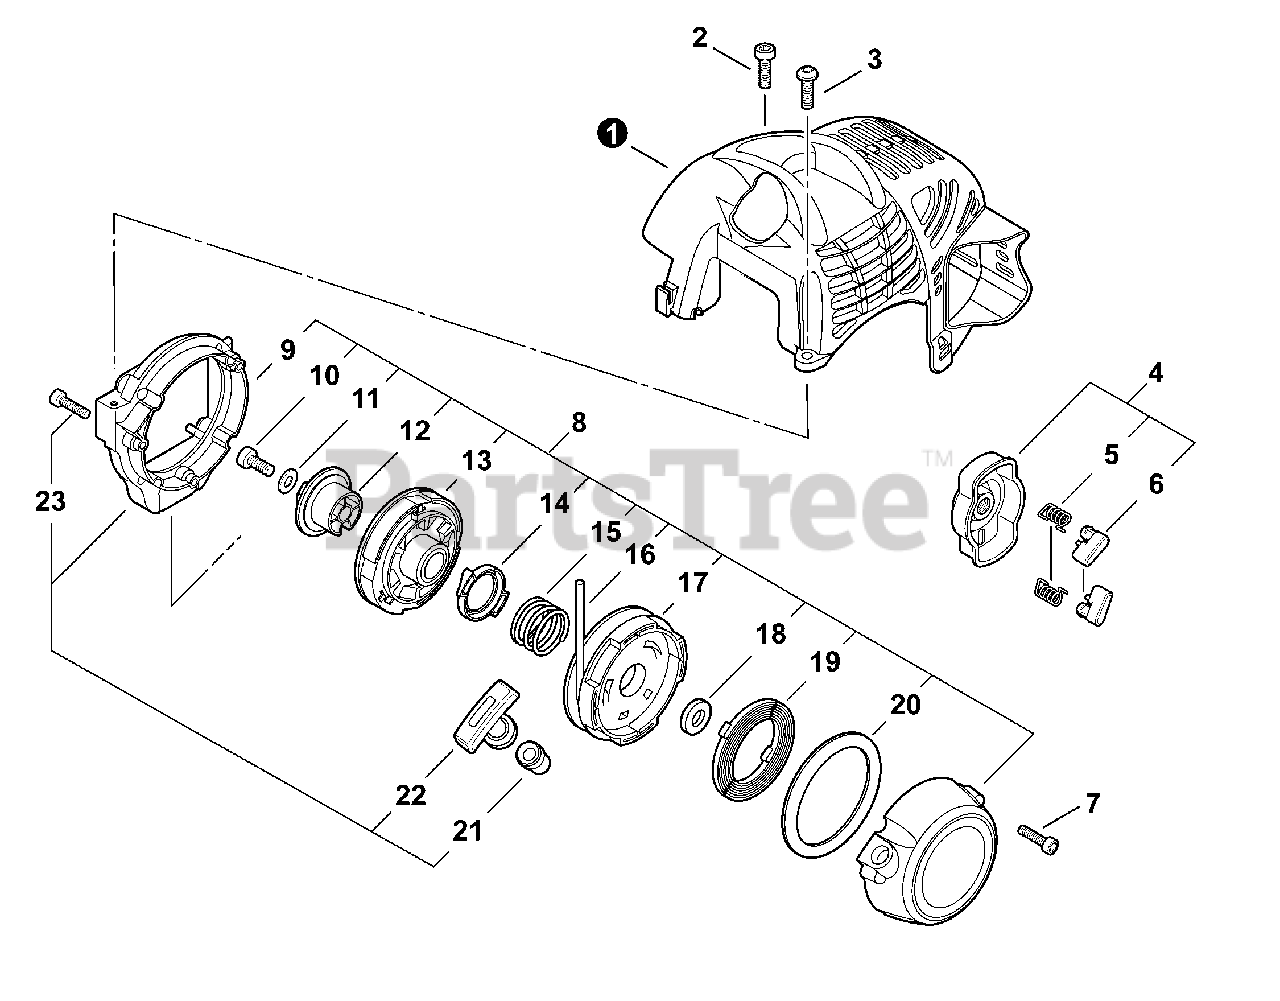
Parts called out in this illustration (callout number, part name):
1	COVER, ENGINE
2	SCREW - 5×16
3	SCREW - 5×16
4	STARTER PAWL ASSY
5	SPRING, RETURN
6	PAWL, STARTER - BLACK
7	SCREW - 4×16
8	STARTER ASSY
9	BRACKET, STARTER
10	SCREW - 5×12
11	WASHER - 5
13	CLUTCH ASSY
16	ROPE, STARTER - 3×900
18	COLLAR - 8
19	SPRING, REWIND
20	PLATE, STARTER
21	GUIDE, ROPE
22	GRIP, STARTER
23	SCREW - 4×16 -- TAPPING
